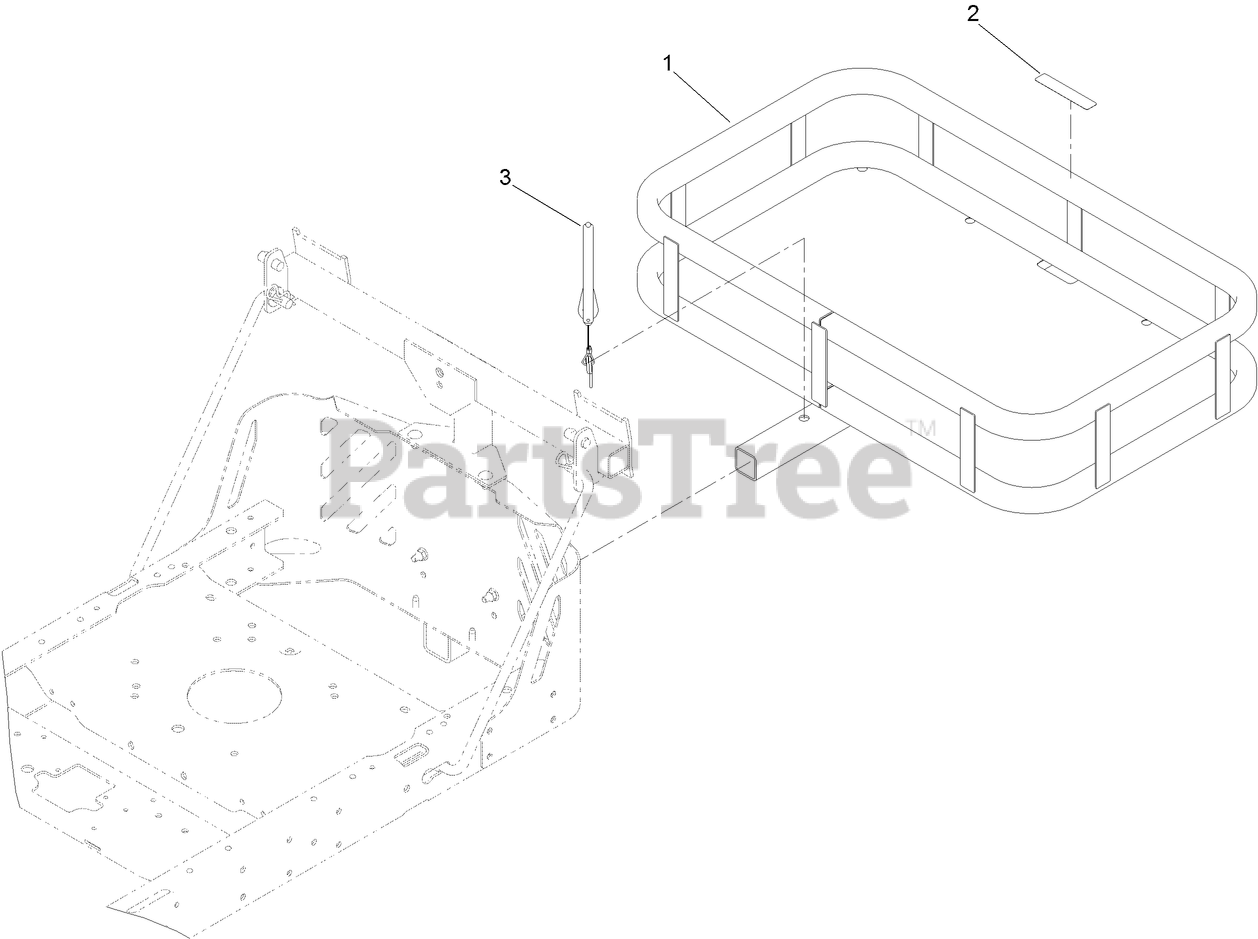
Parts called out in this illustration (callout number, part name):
1	TRAY-CARRIER
2	DECAL-MAXIMUM WEIGHT
3	PIN-ROPS
